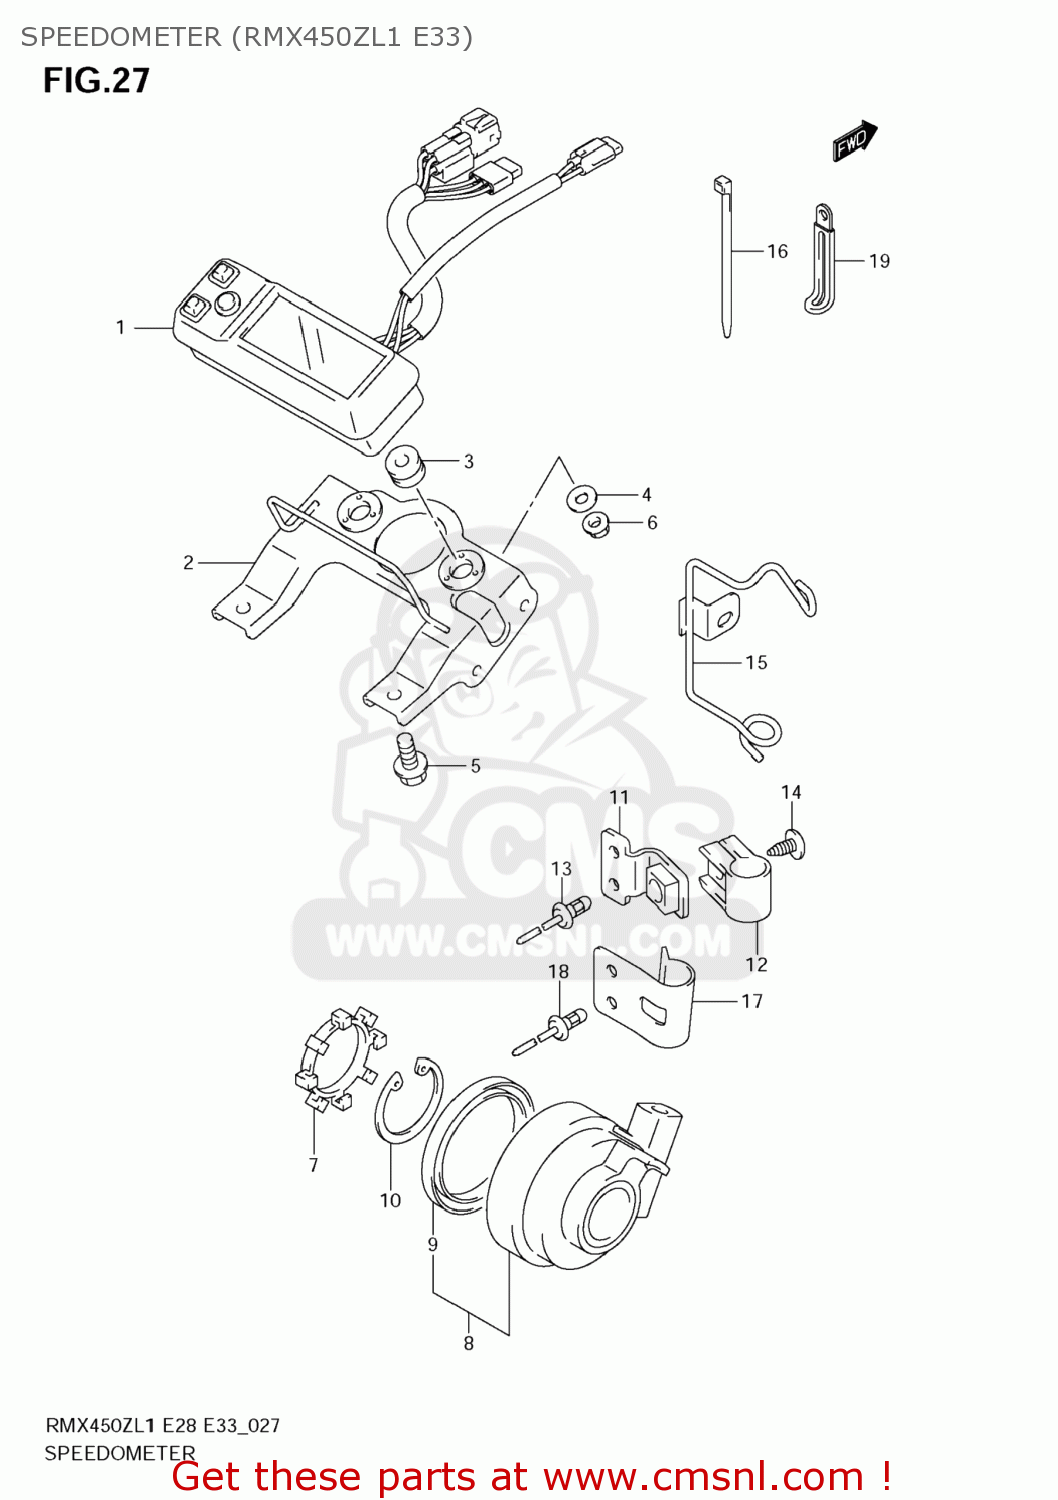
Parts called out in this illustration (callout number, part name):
1	SPEEDOMETER ASSY
2	BRACKET,SPEEDOMETER
3	CUSHION,SPEEDOMETER
4	WASHER(5.5X16X1.2)
5	BOLT
6	NUT
7	ROTOR,SPEED
8	SENSOR,SPEED
9	SEAL,OIL(48X62X7)
10	CIRCLIP
11	GUIDE,SENSOR NO.2
12	CLAMP,BRAKE HOSE
13	RIVET
14	SCREW
15	GUIDE,SENSOR NO.1
16	CLAMP(L:100)
17	GUIDE,SENSOR NO.3
18	RIVET
19	CLAMP(L:45)
